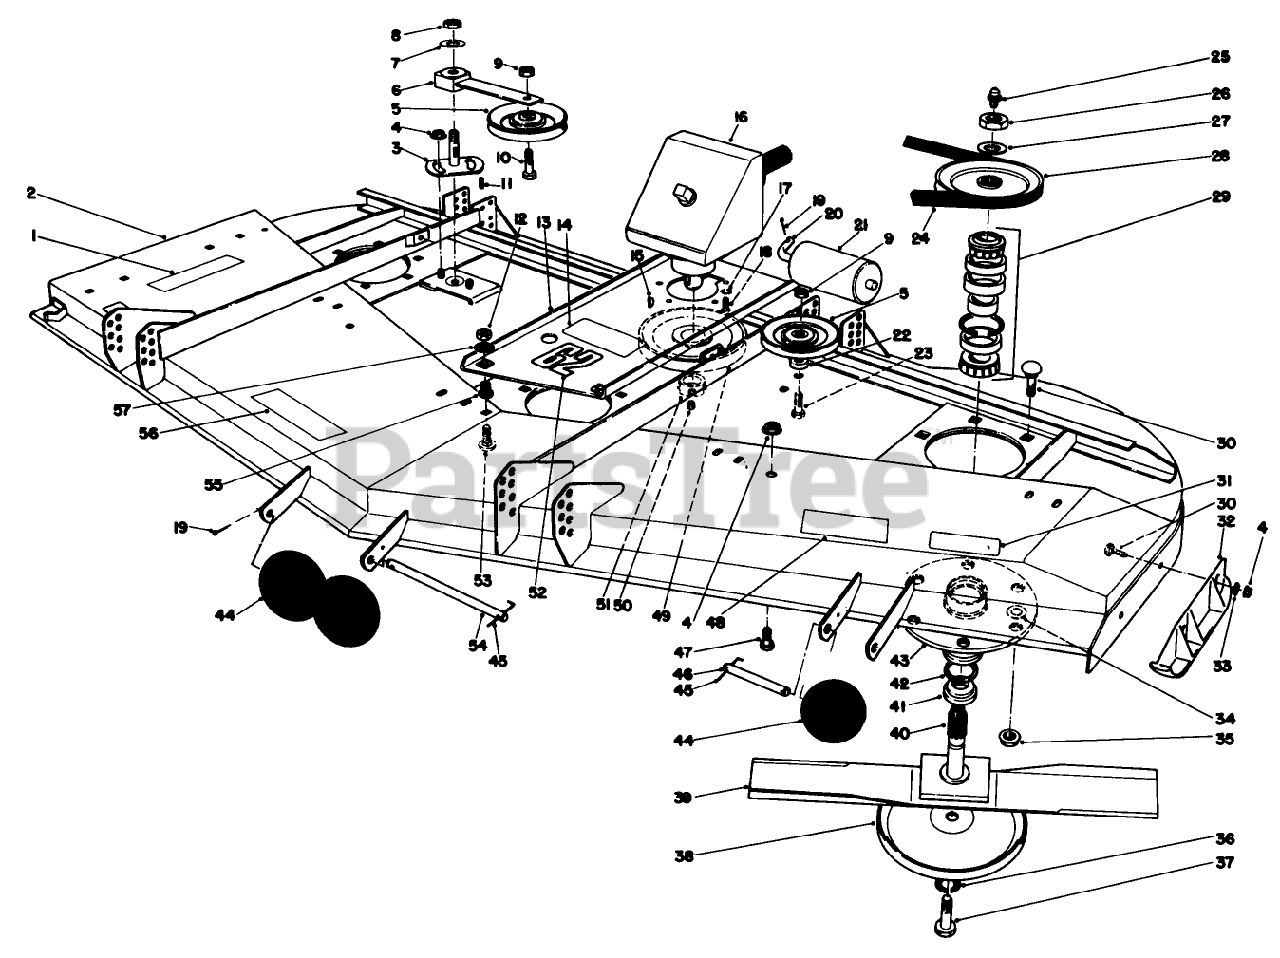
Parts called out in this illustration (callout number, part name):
1	WARNING DECAL
2	Cutting Deck
3	PLATE-IDLER
4	NUT-HHF, WHIZ
5	PULLEY-IDLER
6	IDLER ARM ASM
7	WASHER-FLAT
8	NUT-LOCK, NI
9	NUT-HEX
10	SCREW-HH
11	KEY-SQUARE
12	NUT-LOCK, SIDE
13	GEARBOX BASE WA R
14	Decal-Caution
15	KEY-WOODRUFF
16	GEAR BOX ASM
17	WASHER-LOCK
18	SCREW-HSH
19	PIN-COTTER
20	SHAFT-ROLLER, REAR
21	ROLLER-DECK
22	SPACER
23	SCREW-HH
24	V-BELT
25	FITTING-GREASE
26	NUT-HEX
27	WASHER
28	PULLEY AND HUB ASM
29	BEARING ASM
30	SCREW-CARR
31	DECAL-CAUTION, BLADE
32	Skid
33	LOCKWASHER-PYRAMID
34	WASHER-FLAT
35	NUT-HF
36	WASHER-LOCK
37	SCREW-BLADE
38	Cup-Scalp
39	Blade
40	SHAFT
41	SPACER
42	SEAL-OIL
43	HOUSING-SPINDLE
44	ROLLER
45	PIN-SPECIAL
46	SHAFT-ROLLER
47	SCREW-HH
48	Decal-Rear Weight
49	PULLEY
50	SCREW-SET, HSH
51	BUSHING-LOCK, TAPER
52	DECAL
53	SCREW-CARR
54	SHAFT-ROLLER
55	MOUNT
56	Decal-Caution
57	Washer
